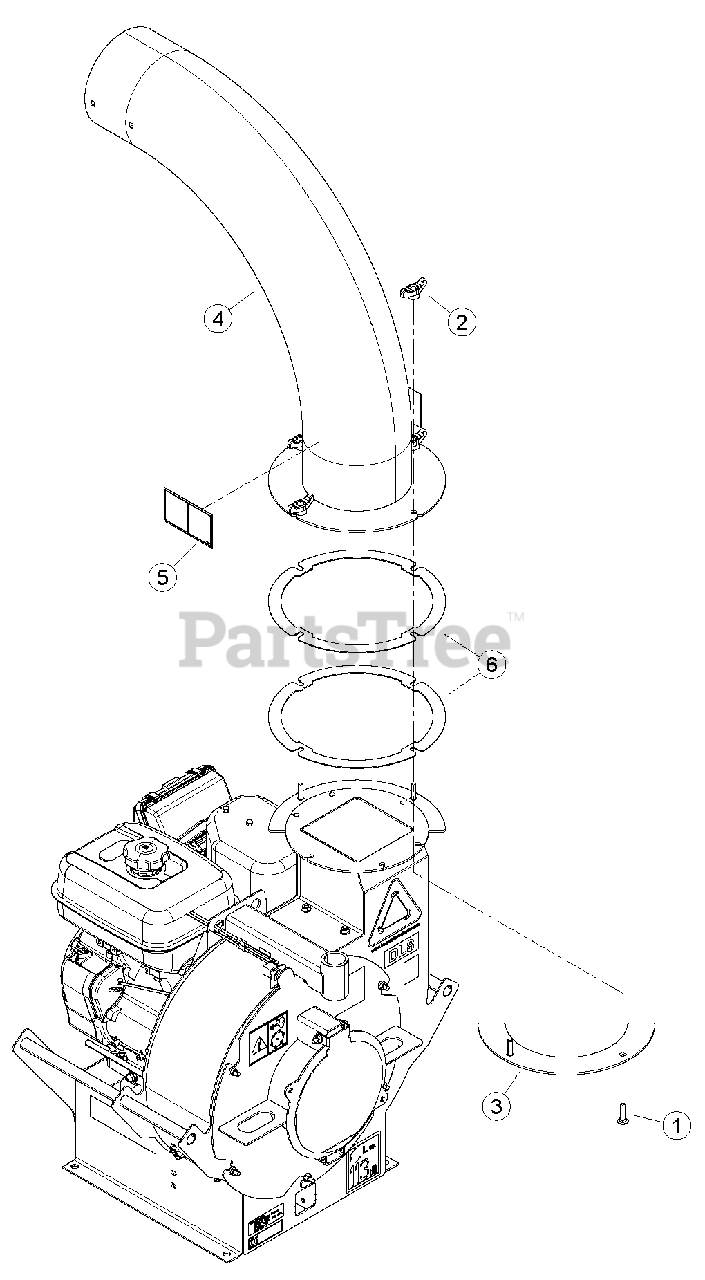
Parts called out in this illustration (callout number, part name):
1	BOLT, 3/8-16 X 1-1/2 GR5 CRG
2	KNOB, 3/8-16 UNC FEMALE TEE
3	RING, DL DISCHARGE
4	ASSEMBLY, DISCHARGE
5	DECAL, DISCHARGE ISO
6	RING, DL DISCHARGE
